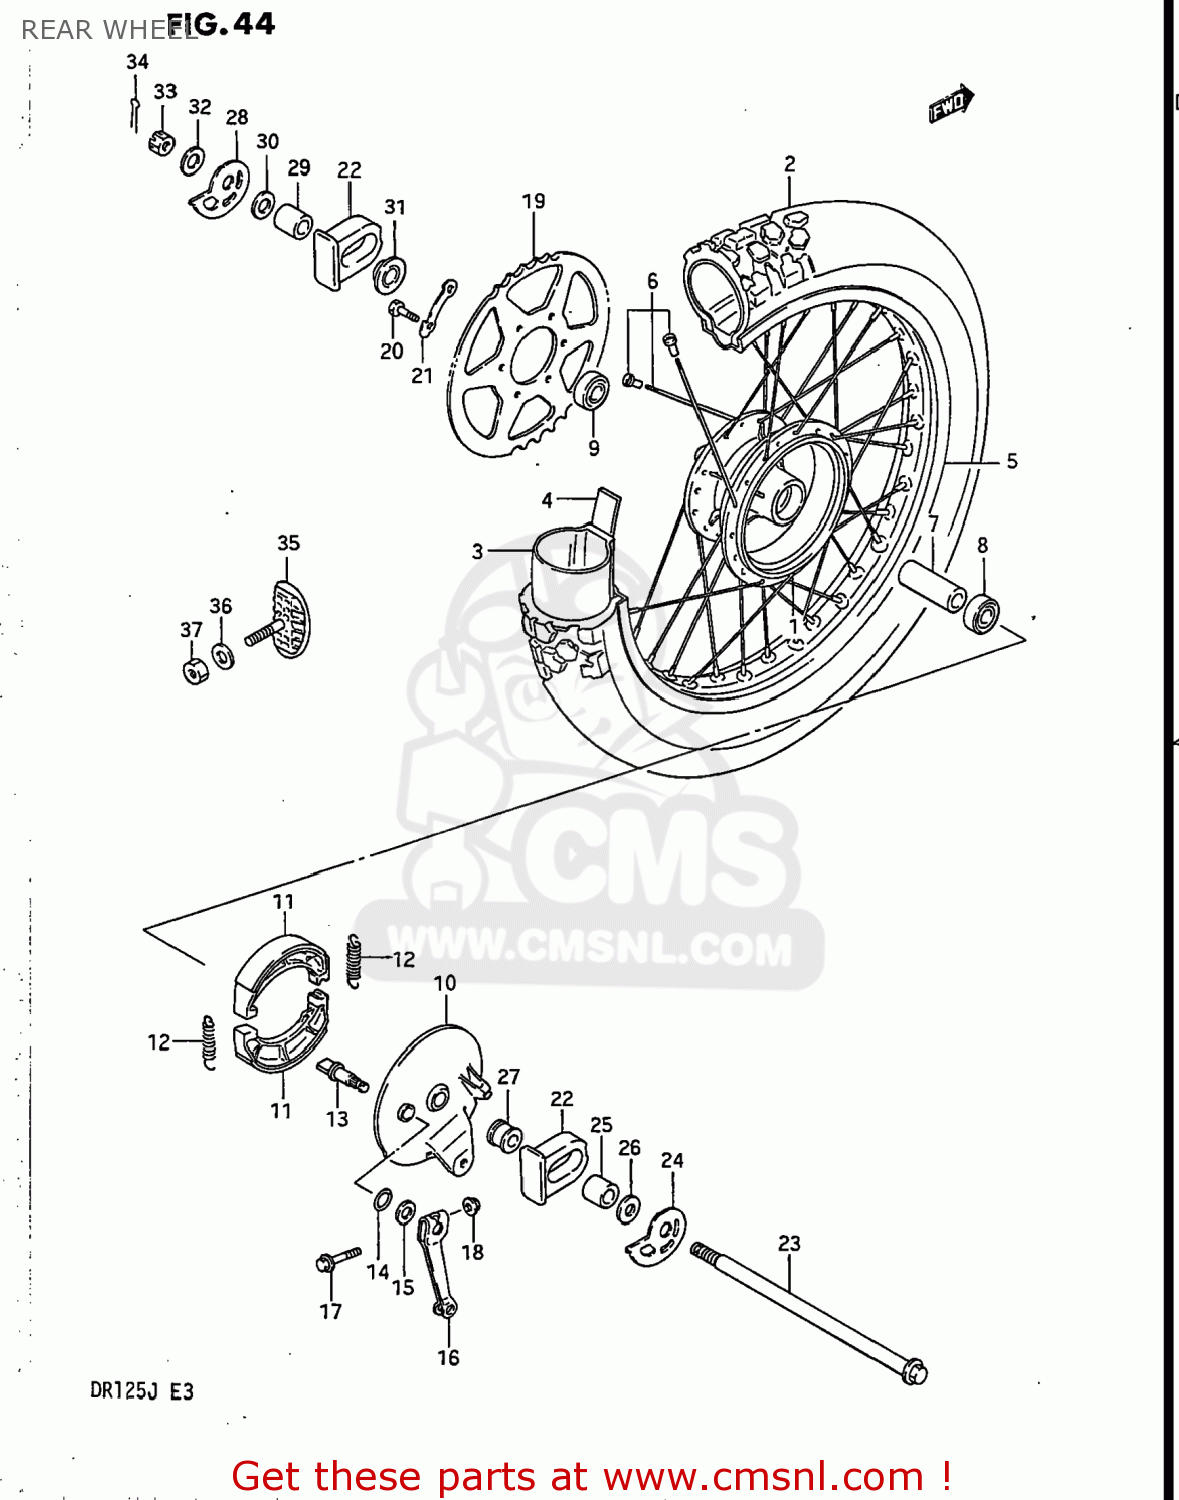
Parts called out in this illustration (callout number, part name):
1	HUB,REAR
2	TIRE,REAR 90/100-18
3	TUBE ASSEMBLY,WHEEL,INNER
4	PROTECTOR,WHEEL,INNER
5	RIM,REAR WHEEL
6	SPOKE SET,RR WHEEL
7	SPACER(15.3X21.7X107.5)
8	BEARING
9	BEARING
10	PANEL,RR BRAKE ANCHOR
11	SHOE,BRAKE
12	SPRING(L:34)
13	CAM,FRONT BRAKE
14	O-RING (D:2.4 ID:13.8)
15	WASHER (14.5X22X1.6)
16	LEVER,RR BRAKE CAM
17	BOLT
18	NUT
19	SPROCKET,REAR
20	BOLT(8X30)
21	WASHER
22	CAP,RR SWINGING ARM
23	AXLE,REAR
24	ADJUSTER,CHAIN,R
25	SPACER,CHAIN ADJUSTER
26	WASHER(15.5X26X2.3)
27	SPACER,RR AXLE,R
28	ADJUSTER,CHAIN,L
29	SPACER,CHAIN ADJUSTER
30	WASHER(15.5X26X2.3)
31	SPACER,RR AXLE,L
32	WASHER
33	NUT 14MM
34	COTTER PIN
35	STOPPER,BEAD
36	WASHER
37	NUT
